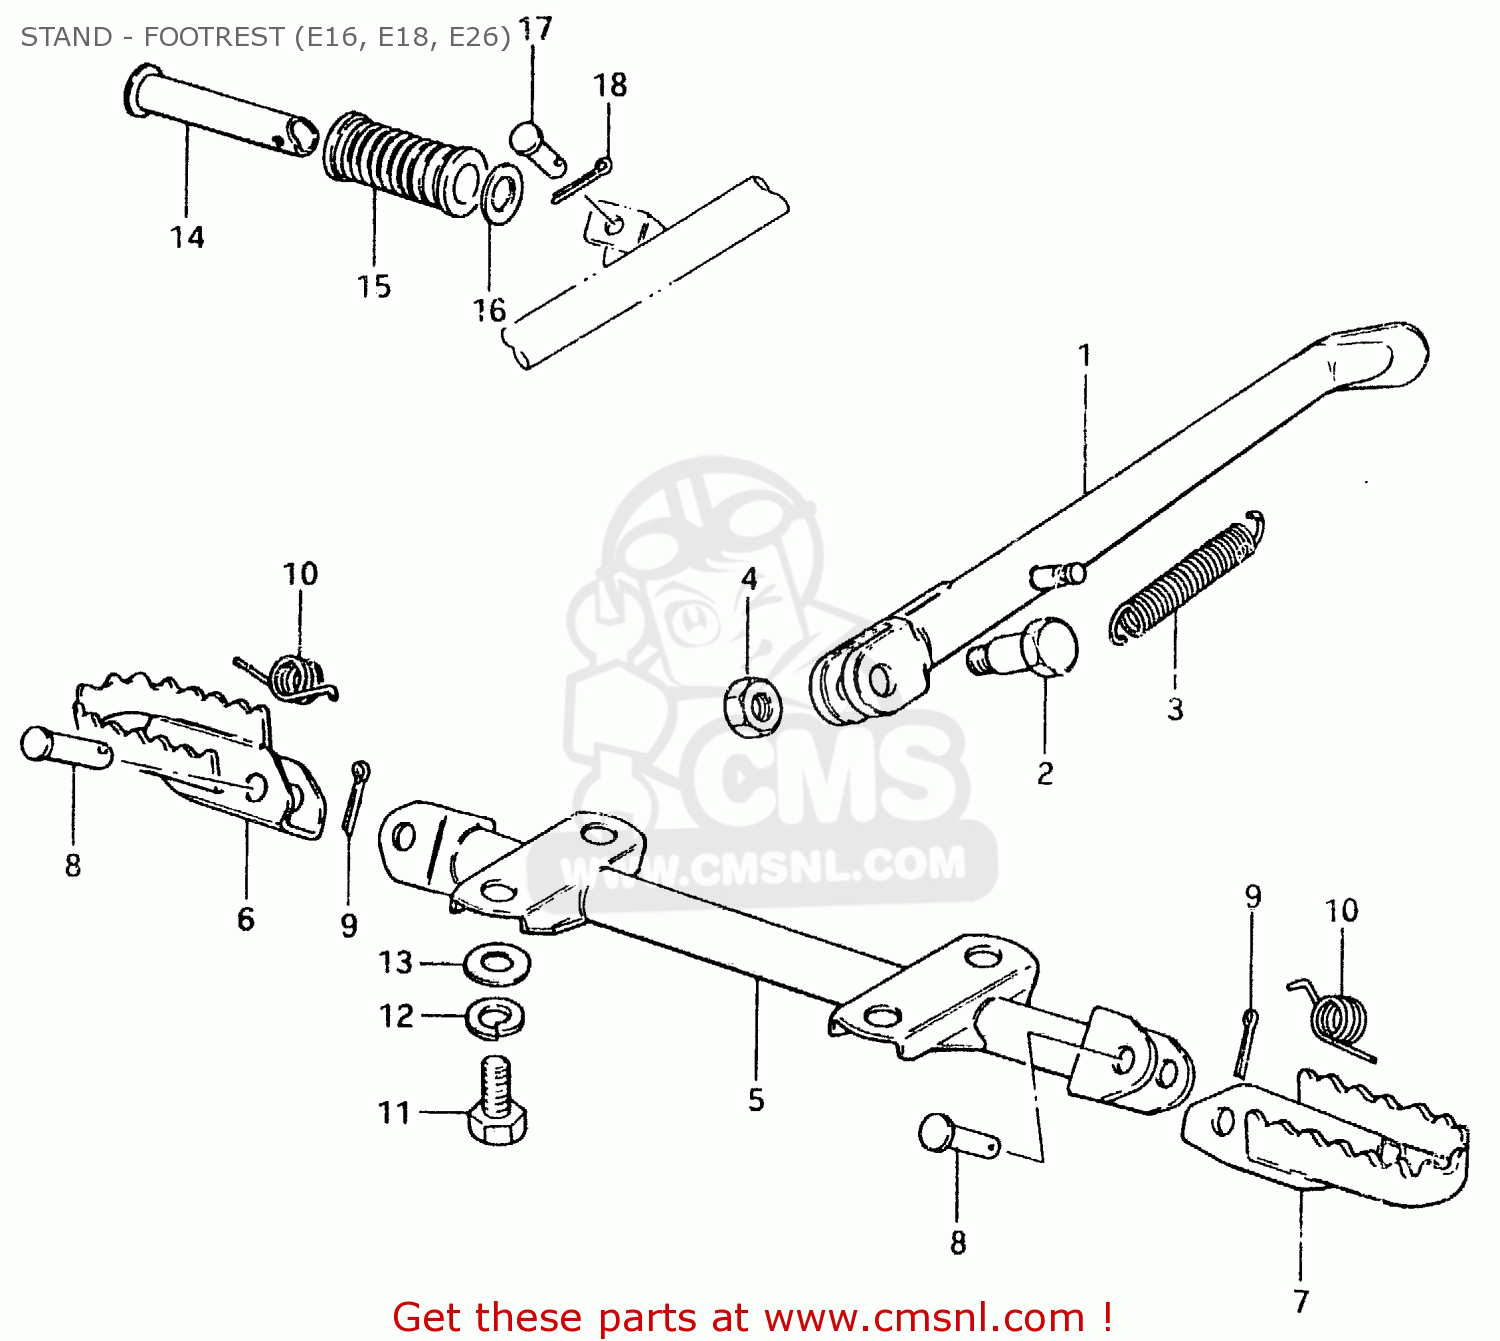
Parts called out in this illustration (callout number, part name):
1	STAND, PROP
2	BOLT
3	SPRING
4	NUT
5	BAR,FR FOOTREST
6	FOOTREST,FRONT
7	FOOTREST
8	PIN
9	PIN 20X20
10	SPRING
11	BOLT
12	LOCK WASHER
13	WASHER
14	BAR,FOOTREST RUBBER
15	RUBBER,PILLION FOOTREST
16	WASHER (19.5X32X2)
17	PIN
18	PIN 20X20
